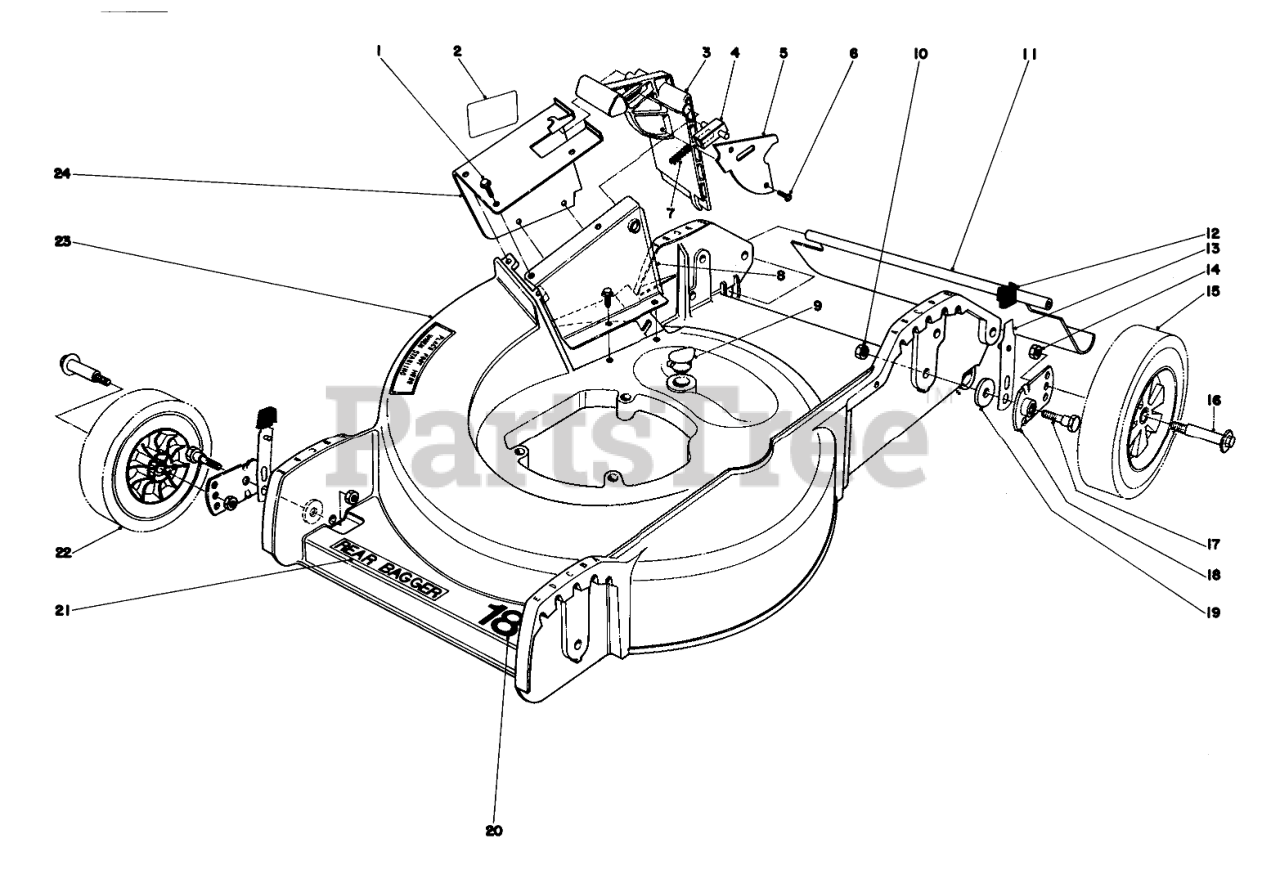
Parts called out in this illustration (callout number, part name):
1	SCREW
2	Decal Door (French & Dutch)
3	Door Mulching
4	Door Latch
5	Cover Door
7	SPRING-COMPRESSION, LATCH
8	Inner Tunnel
9	WASHOUT PLUG
10	Nut
11	SHIELD - TRAILING
12	KNOB-ARM
13	SPRING ARM ASM
14	Nut
15	WHEEL & TIRE ASM
16	BOLT-WHEEL
17	PIVOT SCREW
18	PIVOT ARM ASSY
19	PIVOT WASHER
20	Decal
21	DECK DECAL
22	Wheel & Tire Assembly
23	Housing
24	Tunnel Outer
